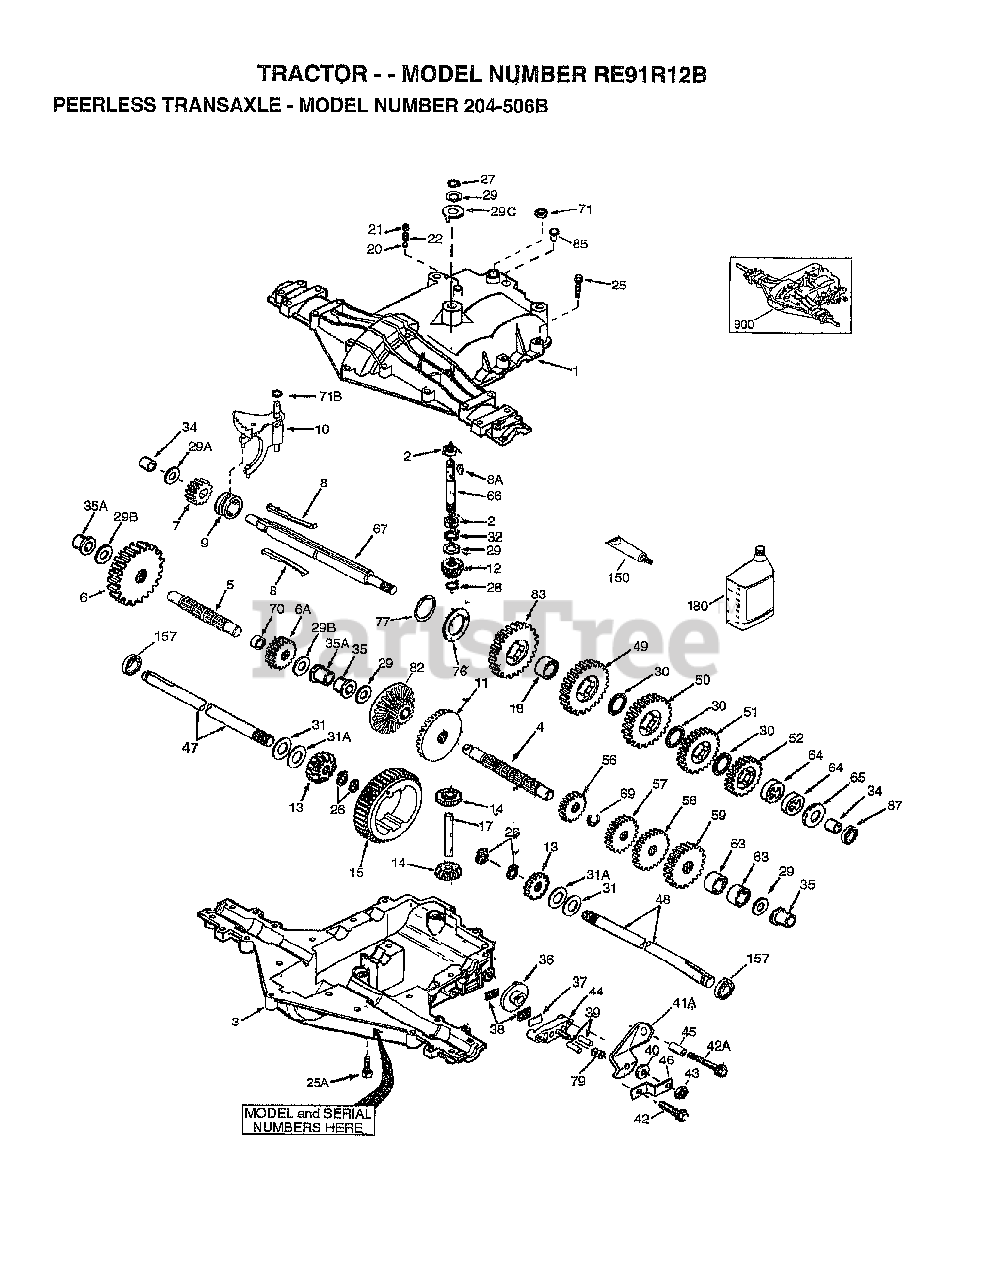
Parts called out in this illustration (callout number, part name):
1	TRANSAXLE COVER
2	NEEDLE BEARING 5/8" ID
3	TRANSAXLE CASE
4	COUNTERSHAFT
5	OUTPUT SHAFT
6	SPUR GEAR (38 TEETH)
6A	SPUR GEAR (15 TEETH)
7	SPUR GEAR (11 TEETH)
8A	KEY, WOODRUFF
9	COLLAR, SHIFTER
10	SHIFT ROD & FORK
11	BEVEL GEAR (30 TEETH)
12	INPUT BEVEL PINION (13TEETH)
13	BEVEL GEAR (13 TEETH)
14	BEVEL PINION (13 TEETH)
15	RING GEAR (43 TEETH)
18	SPACER, NEUTRAL
20	BALL STEEL, 5/16" DIA.
21	SCREW, 3/8-16 X 3/8"
25A	SCREW 1/4-20 X 1-3/8"
26	RING RETAINER
27	RING, RETAINER
28	RETAINING RING
29	WASHER THRUST
29B	WASHER THRUST
30	WASHER THRUST
31A	FLAT WASHER
32	OIL SEAL 5/8"
34	BUSHING 9/16"
35	FLANGED BUSHING 5/8" ID
35A	FLANGED BUSHING 3/4"
37	PLATE BRAKE PAD
41A	BRAKE LEVER
42A	SCREW, 1/4-20 X 2-1/4
43	LOCKNUT 5/16-24
44	HOLDER BRAKE PAD
46	BRKT BRAKE LEVER
49	SPUR GEAR (29 TEETH)
50	SPUR GEAR (23 TEETH)
51	SPUR GEAR (19 TEETH)
52	SPUR GEAR (15 TEETH)
56	SPUR GEAR (11 TEETH)
57	SPUR GEAR (17 TEETH)
58	SPUR GEAR (21 TEETH)
59	SPUR GEAR (25 TEETH)
66	INPUT SHAFT
67	SHIFTER & BRAKE SHAFT
69	RETAINING RING
70	SPACER .890
71	SEAL SQUARE CUT
76	WASHER, THRUST
77	INVERTED RETAINING RING
82	BEVEL & SPUR GEAR (30 & 13 TEETH)
83	SPUR GEAR (27 TEETH)
85	OIL FILL PLUG
87	OIL SEAL 9/16"
150	LIQUID GASKET RTV SILICONE
157	OIL SEAL 3/4"
180	GEAR OIL 80W90
